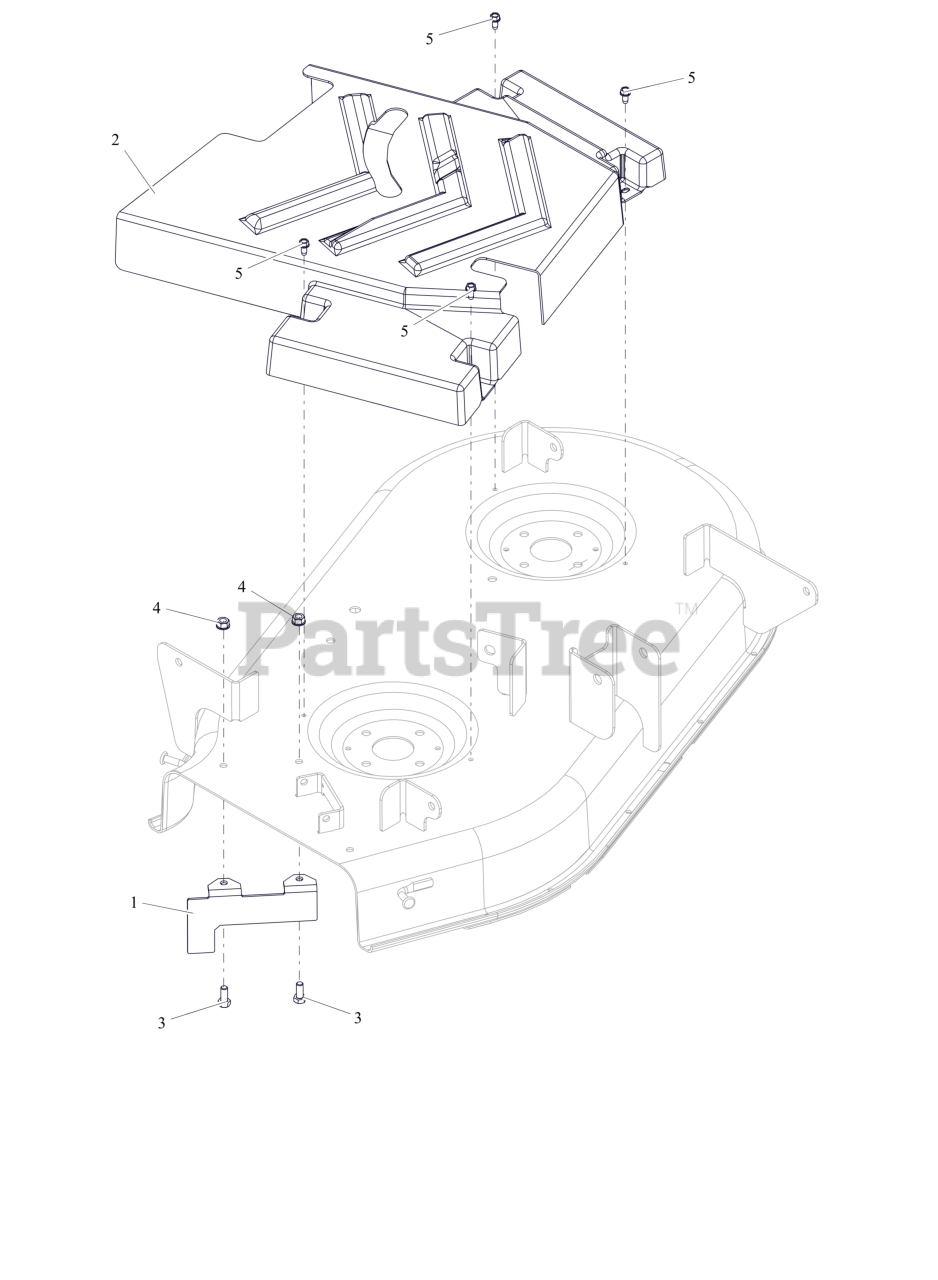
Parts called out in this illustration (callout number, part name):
1	BRKT, BAFFLE , DISCHARGE 34"
2	GUARD, CENTER EDGE 34 DECK
3	BLT,HEX .31-18X.75 G5 ZCC
4	NUT,LK-CTR-FLG .31-18 GF ZCC
5	SCR-TAP .25-20X.50 HWH ZCC
